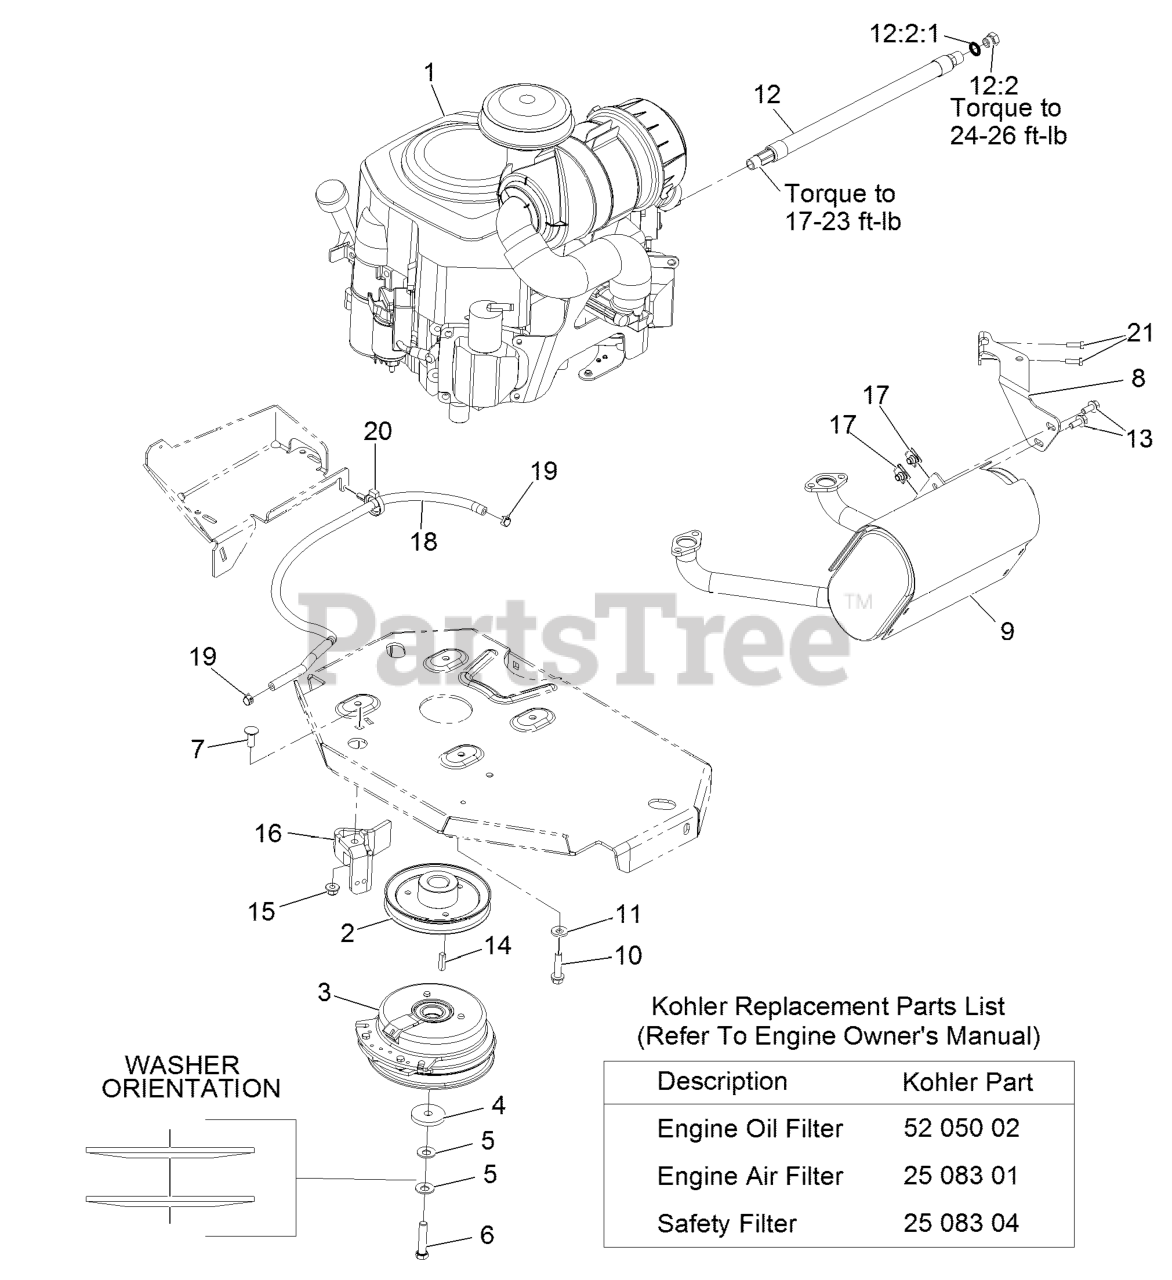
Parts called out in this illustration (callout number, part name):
2	SHEAVE
3	CLUTCH KIT
4	WASHER-CLUTCH
5	WASHER-SPRING
6	SCREW-HH W/LOCTITE
7	SCREW-CARR
8	MUFFLER BRACKET KIT
10	SCREW-HWH
11	WASHER-BELLEVILLE
12	OIL DRAIN HOSE ASM
12:2	PLUG-HH
12:2:1	O-RING
13	SCREW-HHF
15	NUT-HF, NI
16	CLUTCH-ANCHOR
18	HOSE-FUEL
19	CLAMP-HOSE
20	CLAMP-HOSE
21	SCREW-HH M6-1 X 20Mm W/Patch
